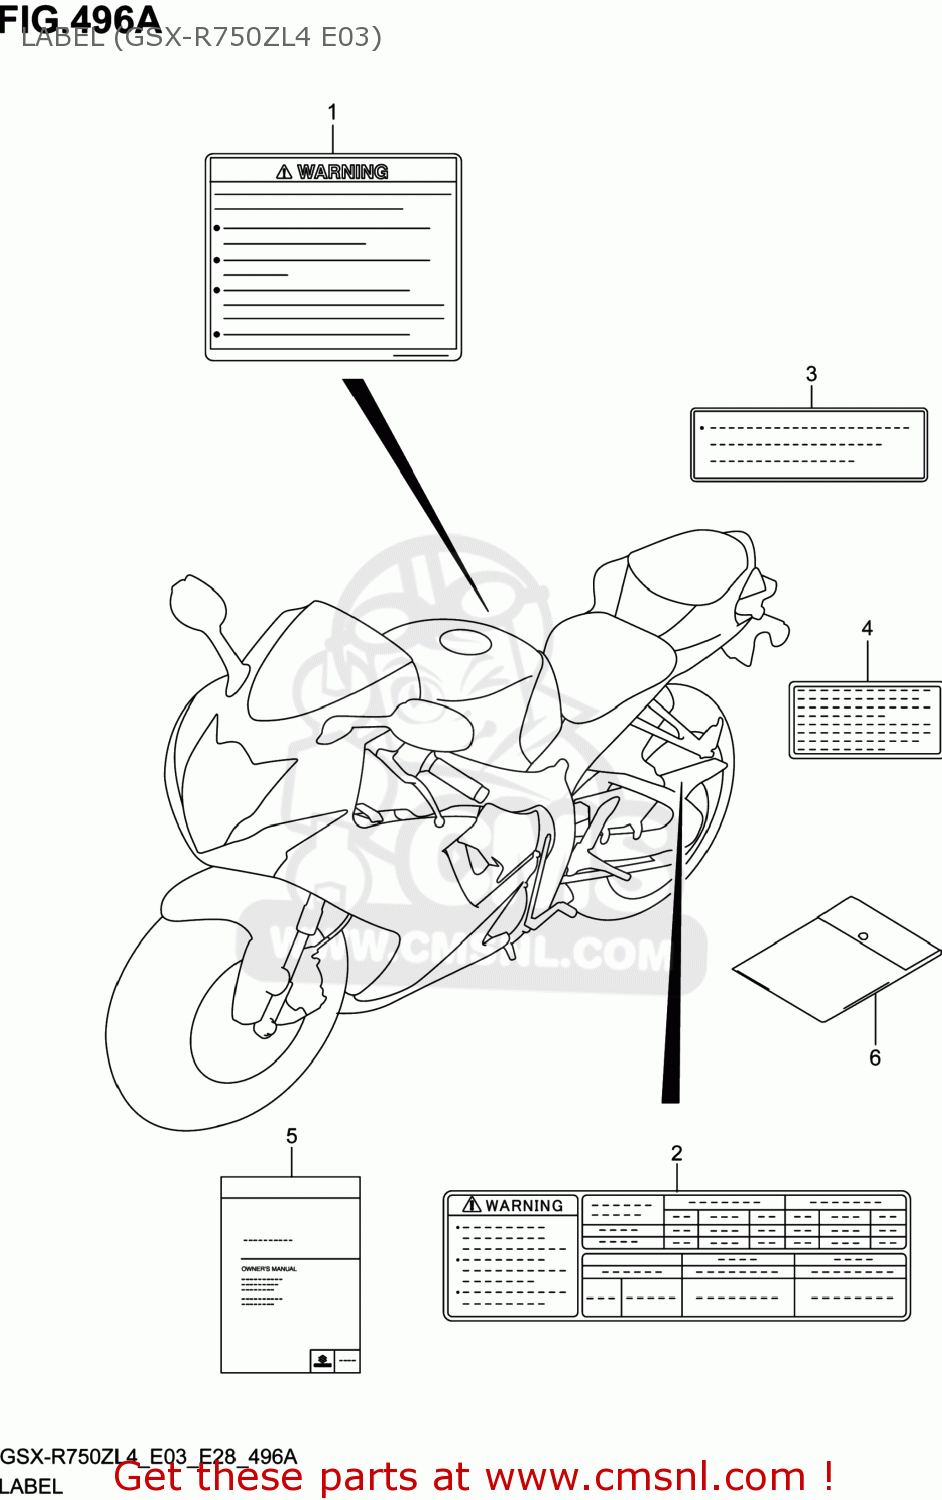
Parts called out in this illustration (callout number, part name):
1	LABEL,GENERAL WARNING
2	LABEL,TIRE INFORMATION
3	LABEL,FUEL INFORMATION
4	LABEL,MANUAL NOTICE
5	MANUAL,OWNER'S
6	BAG,OWNER'S MANUAL
